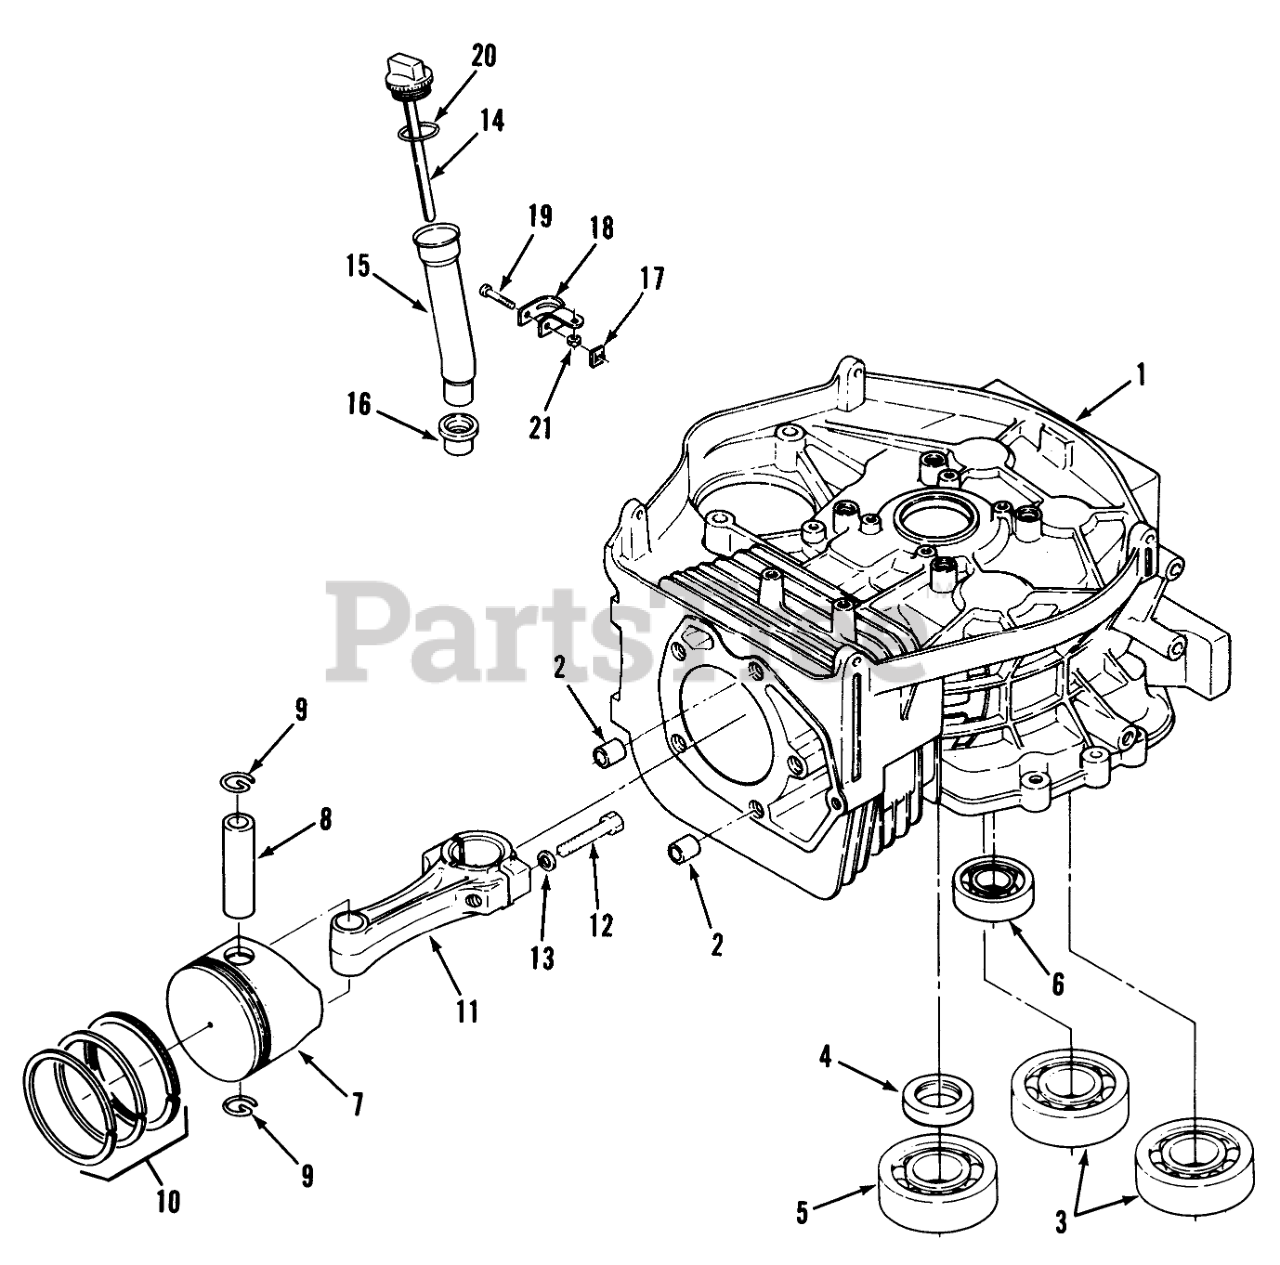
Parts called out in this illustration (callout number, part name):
1	Block-Short
2	PIN-DOWEL HOLLOW
3	BRNG-BALL BAL SHFT L
4	SEAL-OIL CRNKSHFT UP
5	BEARING-BALL CRANKSH
6	BEARING-BALL CAMSHFT
7	Piston Kit-Standard (Includes Pin and Retaining Rings)
8	PIN-PISTON
9	RING-RETAINING
10	Piston Ring Set-Standard
11	Connecting Rod Kit-Standard (Includes Bolts and Washers)
12	Bolt
13	WASHER-CONN ROD
14	INDICATOR
16	Seal
17	Nut
18	BRACKET
19	Screw
20	O-Ring
